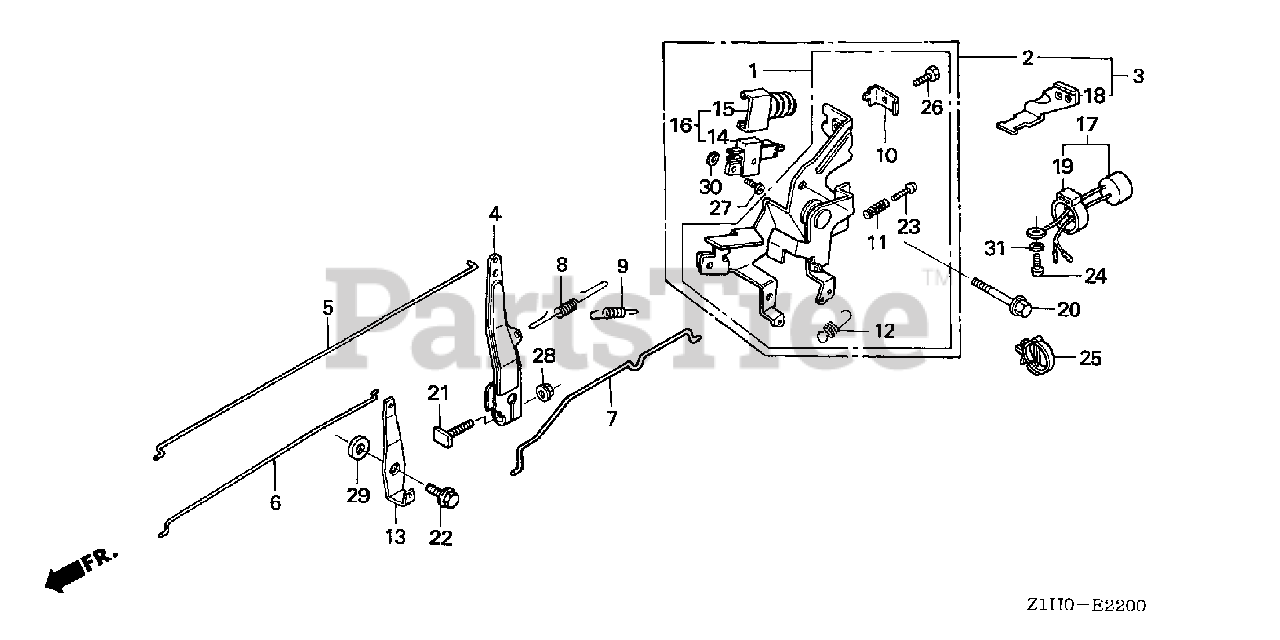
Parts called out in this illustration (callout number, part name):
3	CONTROL ASSY.
4	ARM, GOVERNOR
5	ROD, GOVERNOR
6	ROD, CHOKE
7	ROD, JOINT
8	SPRING, GOVERNOR
9	SPRING, GOVERNOR PRIMARY
10	HOLDER, CABLE
11	SPRING, CONTROL ADJUSTING
12	SPRING, CABLE RETURN
13	LEVER, CHOKE JOINT
14	SWITCH ASSY., ENGINE
15	COVER, SWITCH
16	SWITCH ASSY., ENGINE STOP
17	BUZZER ASSY.
18	STAY, BUZZER
19	SUSPENSION, AUDIBLE PILOT
20	BOLT, FLANGE (6X12) (CT200)
21	BOLT, GOVERNOR ARM
22	BOLT, FLANGE (6MM)
23	SCREW, PAN (5X20)
24	SCREW, TAPPING (5X8)
25	CLIP, HARNESS
26	BOLT, RECESSED (5X16)
27	SCREW, PAN (4X14)
28	NUT, FLANGE (6MM)
29	WASHER, PLAIN (6MM)
30	WASHER, SPRING (4MM)
31	WASHER, SPRING (5MM)
